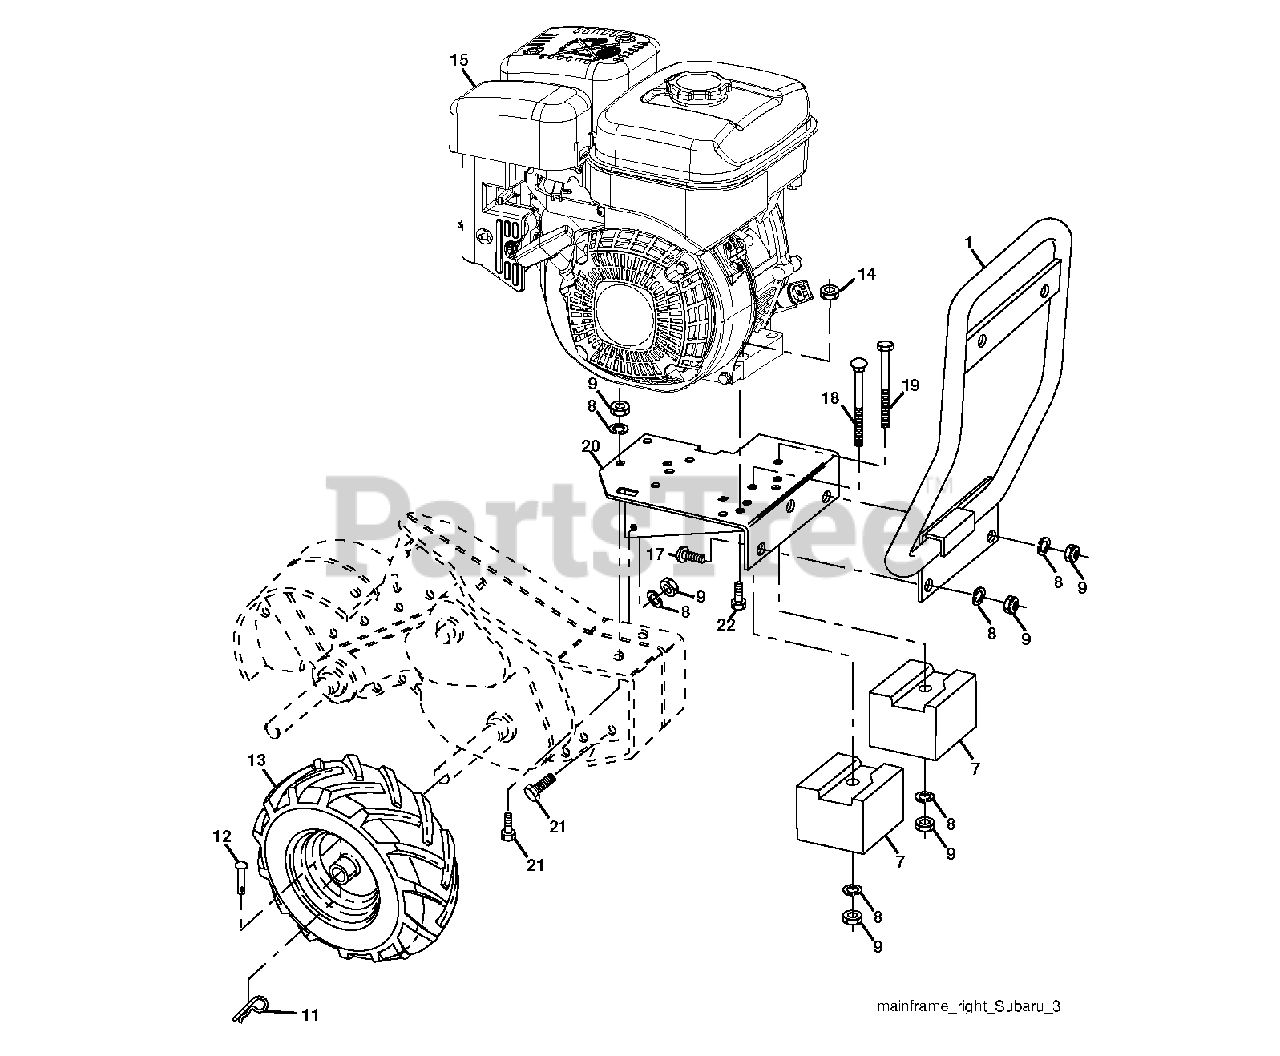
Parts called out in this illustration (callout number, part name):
1	BUMPER.ASM.9HP.TILLER
7	COUNTERWEIGHT
8	WASHER, LOCK 3/8
9	NUT.HEX.3/8-16UNC
11	SPRING TI
13	TIRE.16X4-8.CHEVRON.TILLER
14	LOCKNUT-FLANGE 5/16-18
17	BOLT D
18	BOLT, CARRIAGE 3/8-16X4-1/2
19	BOLT, HEX 3/8-16X4-1/2
20	Base Engine
21	BOLT
22	BOLT
